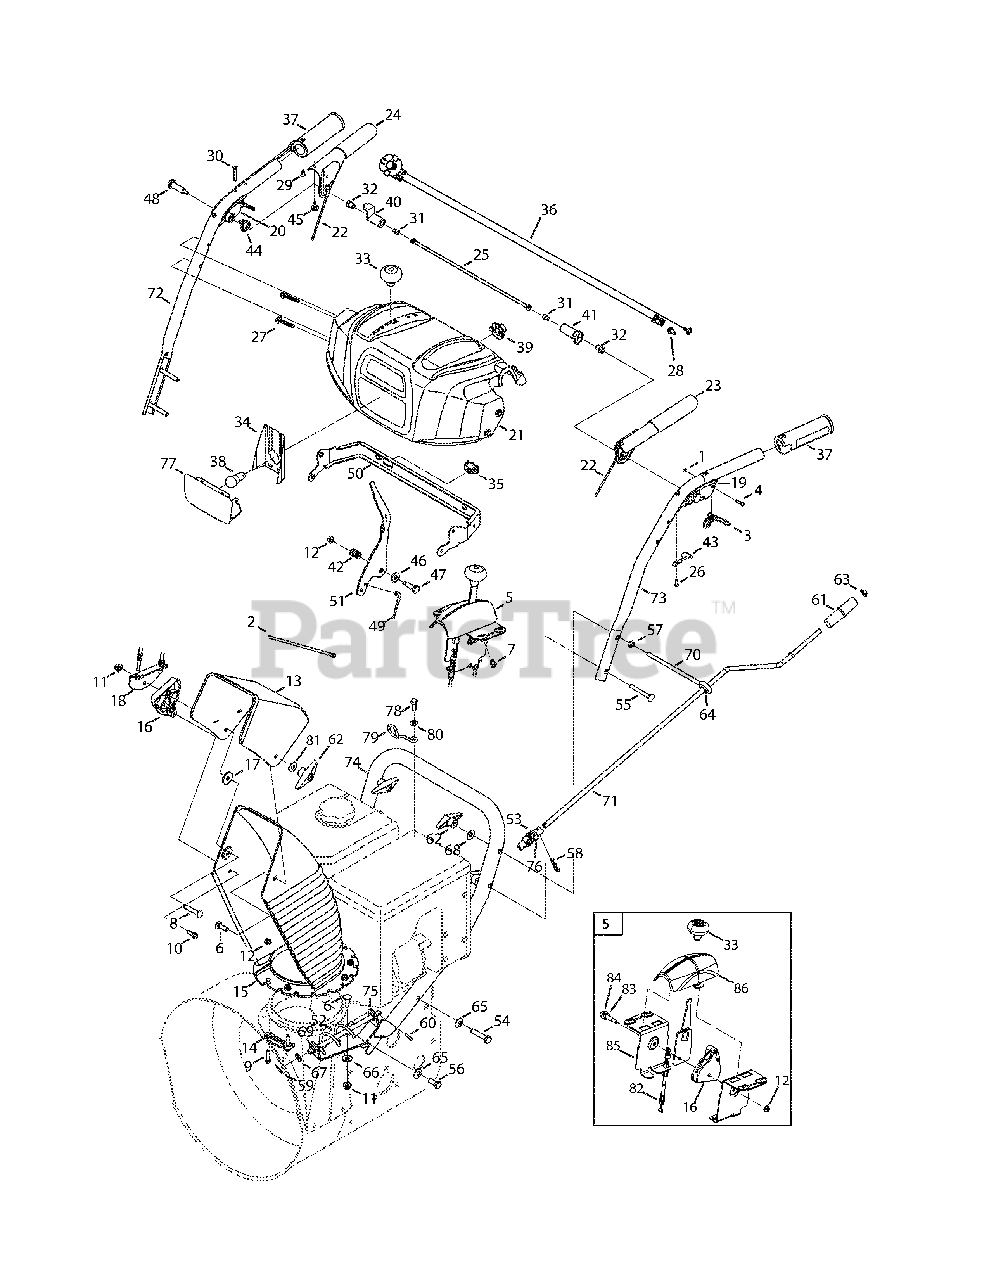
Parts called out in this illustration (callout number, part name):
2	Cable Tie
3	Trigger Lock
5	Chute Control Assembly
6	Carriage Screw, 5/16-18 x 1.0
7	Screw, 1/4-15 x .50
8	Carriage Screw, 5/16-18 x 1.75
9	Hex Screw 1/4-20 x 1.0
10	Screw, 1/4-15 x .750
11	Flange Lock Nut 5/16-18
12	Flange Lock Nut 1/4-20
13	Upper Chute, 6.0
14	Chute Flange Keeper
15	Lower Chute
16	Cbl. Guide, Chute Tilt
17	Flat Wash, .344 x 1.125 x .12
18	Cable Bracket
19	Handle Assembly, LH
20	Handle Assembly, RH
21	Handle Panel
22	Cable Ass’y, Auger/Drive
23	Engagement Handle, LH
24	Engagement Handle, RH
25	Clutch Lock Rod Assembly
26	Screw, #8-16 x .50
27	Screw, 1/4-20 x 1.625
28	Hex Screw, 1/4-20 x .5
29	Screw, #10-16 x .625
30	Screw, #10-24 x 1.375
31	Screw, 1/4-20 x .50
32	Nut, Hex, 1/4-20
33	Shift Knob
34	Lens Lable
35	Heated Grip Switch
36	Wire Harness
37	Heated Grip
38	Lamp, 12.8V
39	Light Socket
41	Clutch Lock Cam
42	Compression Spring
43	Clutch Lock Spring
44	Torsion Spring, .8156 ID x .3038
45	Rubber Bumper
46	Flat Washer, .385 x .87 x .06
47	Screw, Shldr., .374 x 1.05
48	Screw, Shldr., .437 x 1.345
49	Clutch Cable
52	Chute Crank Assembly
53	Joint Block Assembly
54	Hex Screw, 3/8-16 x 2.00
55	Carriage Screw, 5/16-18 x 2.5
56	Screw, Hex, 3/8-16 x 1.00
57	Nut, Hex, 5/16-18
58	Internal Cotter Pin
59	Pin, Bow-tie Cotter
60	Spring Pin, .156 dia. x .875 Lg.
61	Knob, Crank
62	Knob, Wing Nut, 5/16-18
63	Push Cap, 3/8
64	Rubber Grommet
65	Bell Wash, .375 x .87 x .063
66	Flat Washer, .349 x .879 x .063
67	Flat Wash, .375 x .738 x .063
68	Wash, Bell, .34 x .872 x .06
69	Plastic Bushing, .38 ID
70	Eye Bolt, .70 Dia.
71	Chute Rod, .375 Dia. x 29.72
72	Handle, Upper, RH
73	Handle, Upper, LH
74	Handle, Lower
75	Chute Crank Bracket
76	Roll Pin, 3/16 Dia. x 1.100
78	Hex Screw, M8-1.25
79	Cable Guide
80	Flat Washer, .330 x .630 x .0635
81	Washer, Flat, .349 x .879
82	Cable, Chute Tilt
83	Washer, Spring, .39 x .625 x .012
84	Screw, Shoulder, .31 x .995:1/4-20
85	Bracket, Mounting
86	Cover, Tilt Cover
